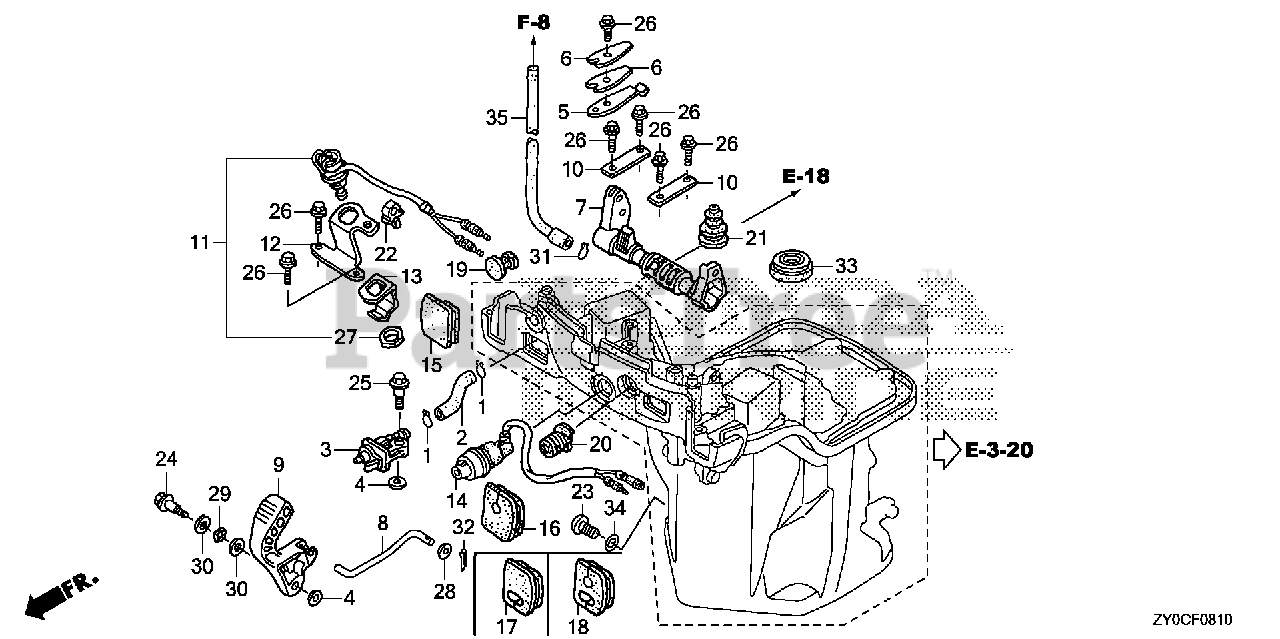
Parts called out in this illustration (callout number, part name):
1	CLIP, TUBE (ENGINE NO.)
2	TUBE A, FUEL (FKM)
3	CONNECTOR ASSY., FUEL (B)
4	WASHER, PIVOT
5	SPRING, CLICK
6	SPRING, CLICK ASSIST
7	SHAFT, SHIFT
9	LEVER, SHIFT
10	PLATE, SHIFT SHAFT
11	SWITCH ASSY., NEUTRAL
12	BRACKET, NEUTRAL SWITCH
13	PLATE, NEUTRAL SWITCH
14	LAMP ASSY., INDICATOR
15	GROMMET A, OIL CASE
18	GROMMET B, OIL CASE
19	GROMMET F, OIL CASE
20	GROMMET D, OIL CASE
21	GROMMET E, OIL CASE
22	CLIP, BRAKE PIPE (A) (FOR NEUTRAL SWITCH)
23	BOLT, OIL CHECK
24	BOLT, REVERSE LOCK
25	BOLT, SPECIAL (6X22) (CT200)
26	BOLT, FLANGE (5X12) (CT200)
27	NUT, HEX. (20MM) Use up to Frame SN 1300359.
28	WASHER, PLAIN (5MM)
29	WASHER, WAVE (10MM)
30	WASHER, PLAIN (9MM)
31	CLIP, TUBE (B10)
32	PIN, SPLIT (2.0)
33	SEAL, WATER (15X28X6) (ENGINE NO.)
34	O-RING (6.9X1.45)
35	TUBE, WATER CHECK
